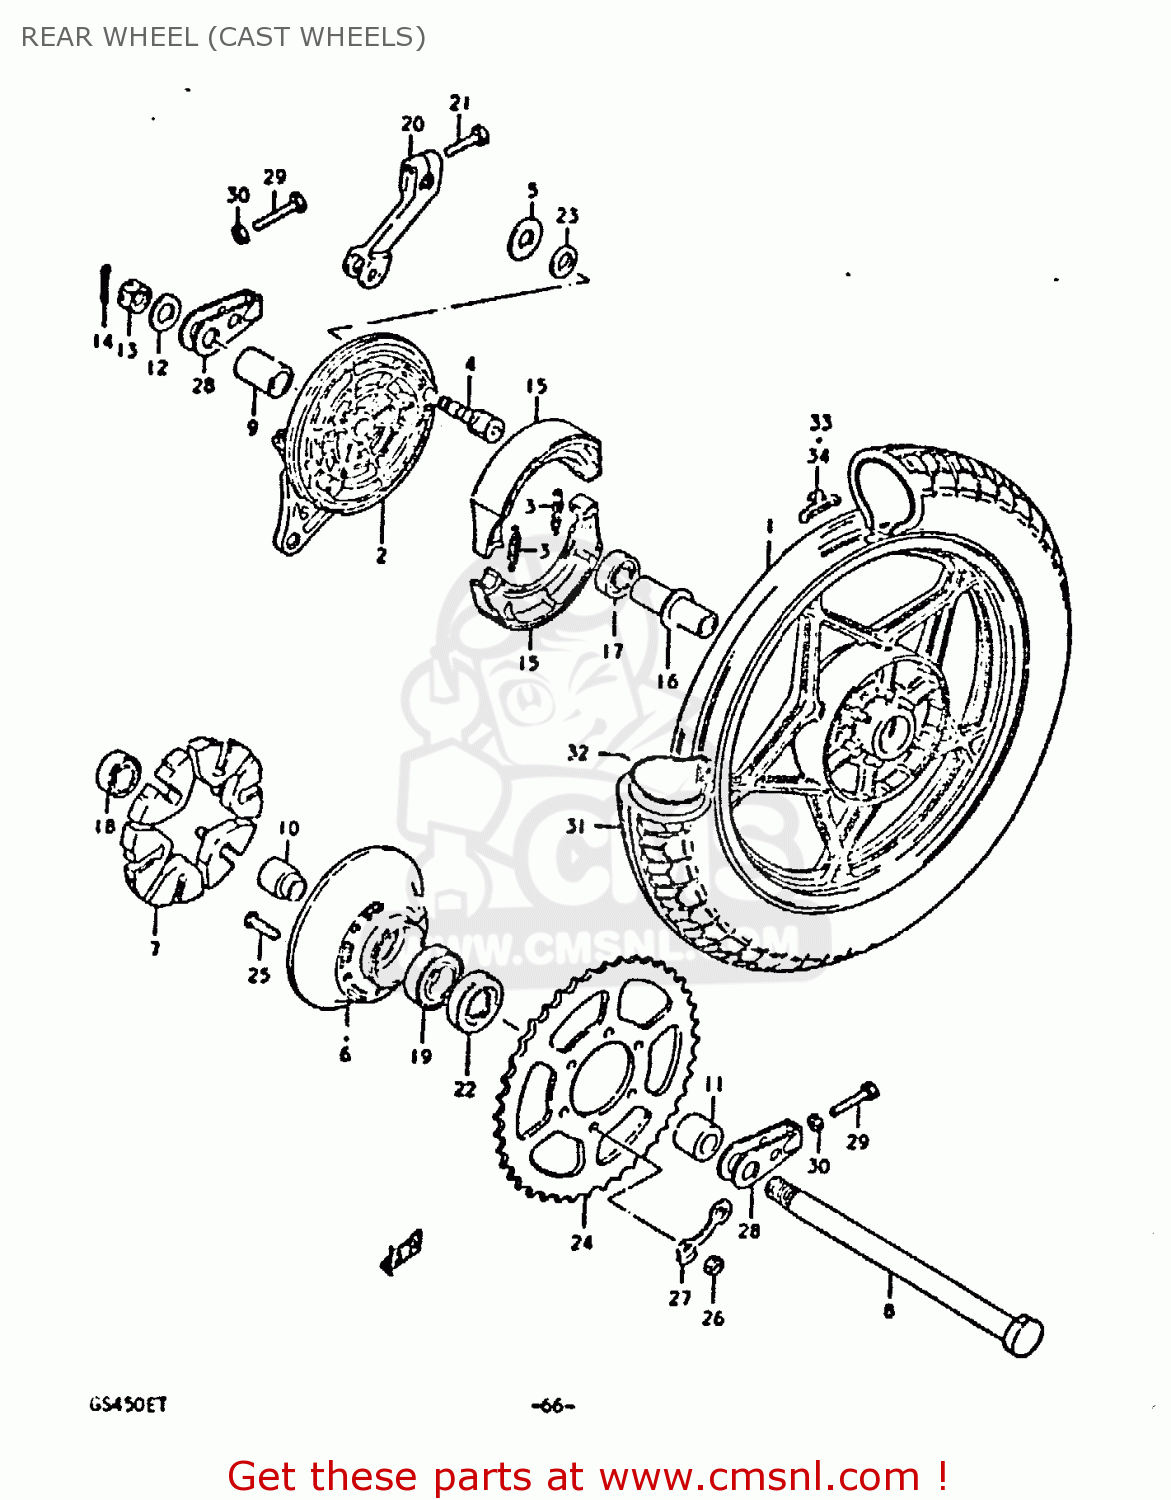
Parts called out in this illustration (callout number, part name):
1	WHEEL,REAR
2	PANEL,REAR HUB
3	SPRING,BRAKE SHOE
4	CAM,FRONT BRAKE
5	WASHER (15X24X1.6)
6	DRUM,REAR SPROCKET MOUNT
7	ABSORBER,RR HUB SHOCK
8	AXLE,REAR
9	SPACER(17.5X28X44.8)
10	SPACER,REAR HUB BEARING
11	SPACER(17X30.5X22.3)
12	WASHER (17X30X3.2)
13	NUT
14	PIN,COTTER
15	SHOE SET,BRAKE
16	SPACER (17.6X24X57)
17	BEARING
18	BEARING
19	BEARING
20	LEVER,REAR BRAKE CAM
21	BOLT
22	OIL SEAL
23	O-RING,BOSS
24	SPROCKET,RR
25	BOLT
26	NUT
27	WASHER
28	ADJUSTER,CHAIN
29	BOLT
30	NUT
31	TIRE
32	TUBE ASSEMBLY,WHEEL,INNER
33	BALANCER,WHEEL
34	BALANCER,WHEEL
